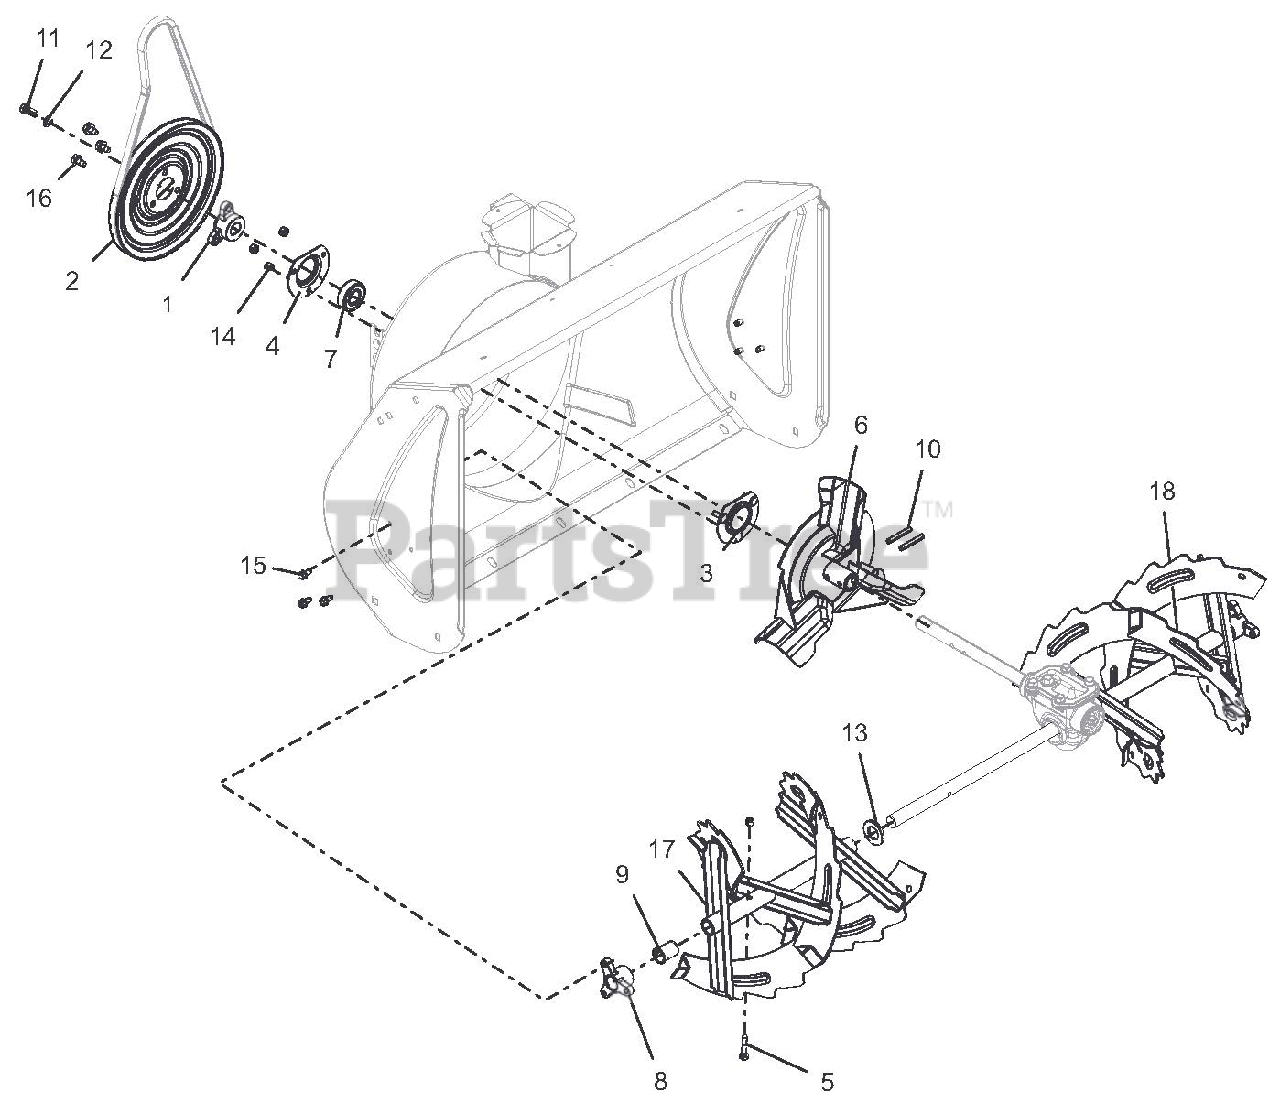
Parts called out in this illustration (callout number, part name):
1	PULLEY HUB, BOLT-ON D-BORE .75
2	PULLEY,SPIN FORM SINGLE GROOVE
3	BEARING FLANGE
4	BEARING FLANGE
5	SHEAR BOLT
6	IMPELLER, COMPACT 12" 3-BLADE
7	BRG-BALL .750X1.750X.50
8	BUSHING, RAKE SHAFT .75"
9	BSHG-FLG SPLIT NYLINER .75"ID
10	PIN-ROLL .250X1.75
11	BLT-HEX .31-24X.75 YWZC GR5
12	WSHR-LK .312X.097 HVY YWZC
13	@WSHR-FL-STL.812X1.50X.135YWZC
14	@NUT-LK-CTR .25-20 YWZC
15	SCR-TAP .25-20X.50 HWH TR YWZ
16	@SCR-TAP .31-18X.50 HWH TR YWZ
17	RAKE, 28" RH, BLK SERR W/ZERK
18	RAKE, 28" LH, BLK SERR W/ZERK
